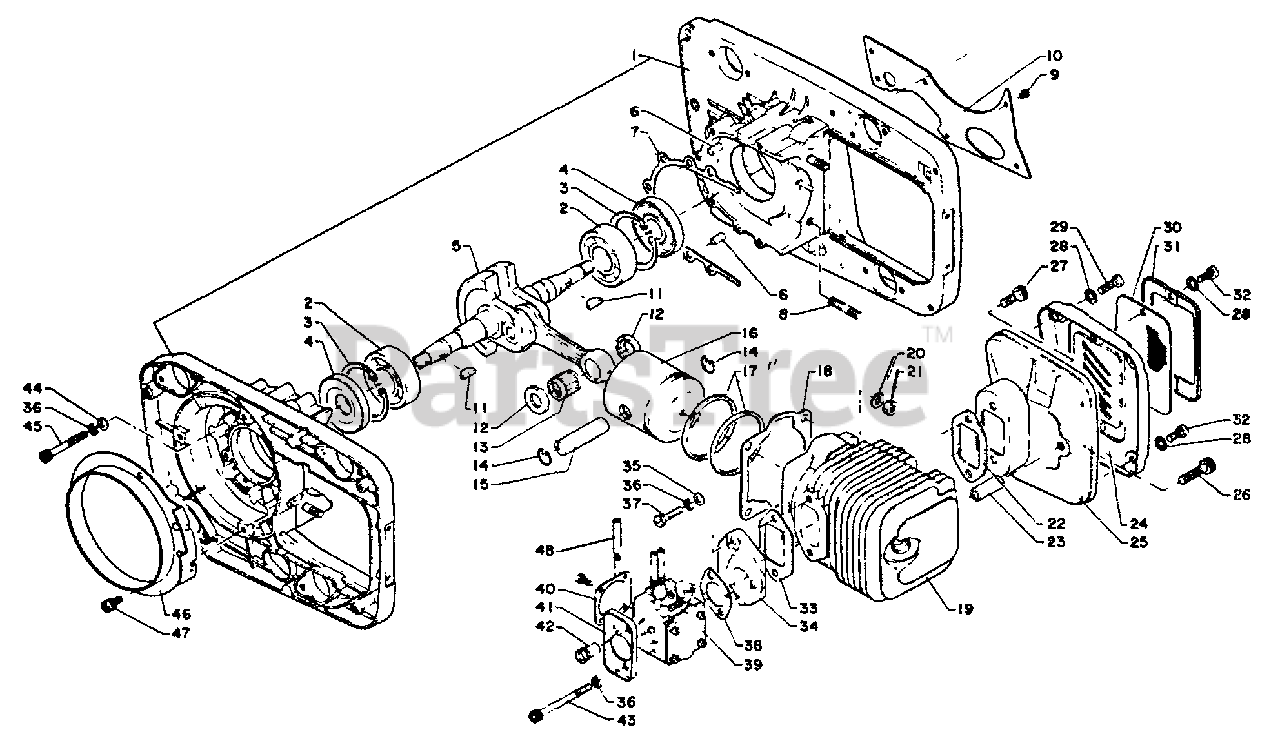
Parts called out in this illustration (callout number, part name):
1	CRANKCASE KIT
2	BEARING, BALL - 6204C3
3	RING, RETAINING - 47
4	SEAL, OIL
5	CRANKSHAFT ASSY
6	PIN - LOCATING
7	GASKET, CRANKCASE
8	STUD
9	RIVET
10	SEAL, DUST
11	KEY - 3X14
12	SPACER, PISTON
13	BEARING, NEEDLE
14	RING, RETAINING
15	PIN, PISTON
16	PISTON
17	RING, PISTON
18	GASKET, CYLINDER
19	CYLINDER
20	WASHER - 6
21	LOCKNUT - 6
22	GASKET, EXHAUST
23	SPACER
24	LID, MUFFLER
25	MUFFLER
26	SCREW - 6X30
27	SCREW - 6X15
28	LOCKWASHER - 5
29	SCREW - 5X16
30	SCREEN, SPARK ARRESTOR
31	RETAINER, SCREEN
32	SCREW - 5X8
33	GASKET, INTAKE
34	INSULATOR, INTAKE
35	WASHER
36	LOCKWASHER - 5
37	SCREW - 5X30
38	GASKET, INTAKE
39	CARBURETOR SDC-76
40	COVER, CARBURETOR
41	ADAPTOR, INTAKE
42	GROMMET
43	SCREW - 5X55
44	WASHER - 5
45	SCREW - 5X40
46	SEAL, DUST
47	SCREW - 5X10
48	TUBE
